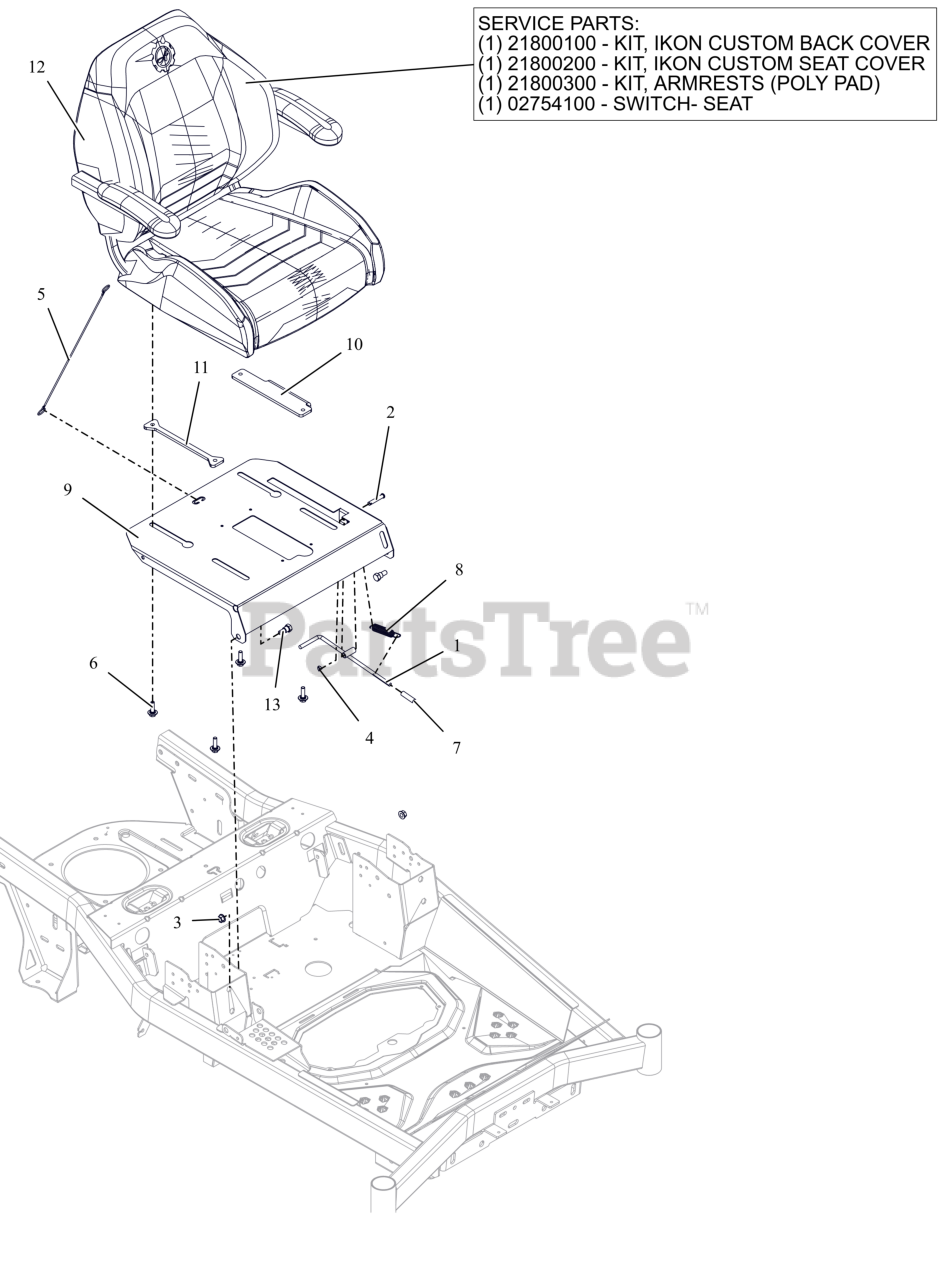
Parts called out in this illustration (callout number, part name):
1	WLDMT, LATCH SEAT (BLACK)
2	PIN, CLEV .309X1.75 ZCC
3	NUT-LK-CTR-FLG .375-16 GF ZCC
4	NUT-PUSH .312
5	LANYARD, SEAT CABLE .093X19.5
6	BLT, SHLDR .31-18 X .100
7	GRIP, BLACK RD-.312X1.50
8	SPRG, EXTENSION .063 X .653 X 2.755
9	PLATE-SEAT
10	PLATE- SEAT ADJUSTER
11	PLATE, ADJ SEAT SLIDE (BLACK)
12	SEAT- IKON 2023 (WOOD)
12	KIT - IKON CUSTOM BACK COVER
12	KIT - IKON CUSTOM SEAT COVER
12	KIT - ARMRESTS (POLY PAD)
12	SWITCH- SNAP MTG N.O.
13	BLT-SHLDR .50X.38 ZCC
